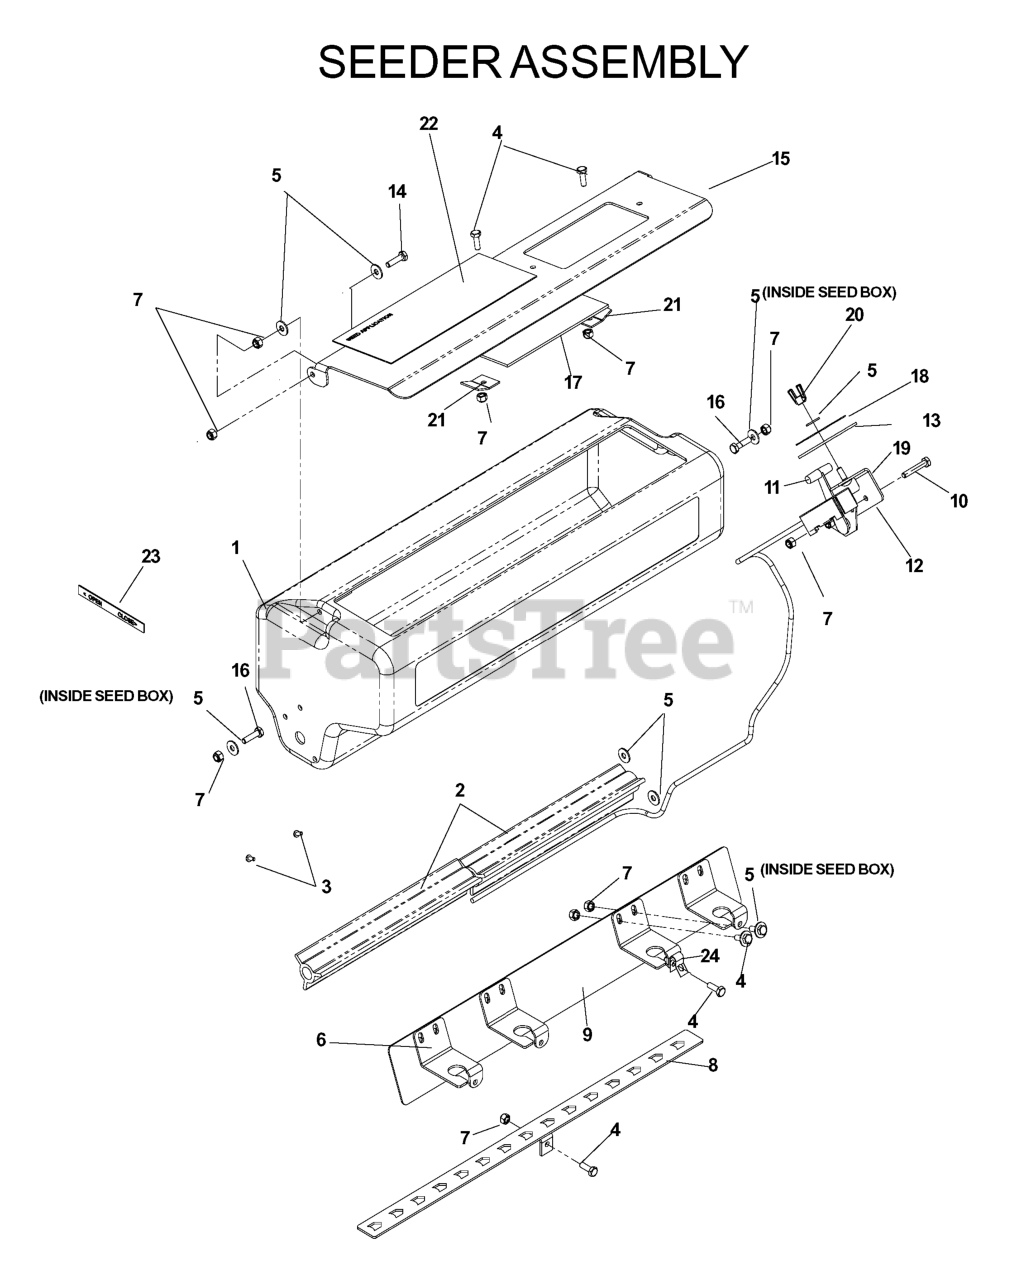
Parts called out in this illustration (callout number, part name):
1	SEED BOX CHARCOAL GREY
3	HR STRIP, 1/8 X 1
4	HCS 1/4C X 3/4 HCS
5	WASHER 1/4 FLAT
7	NUT.1/4-20.HEX.NYLOC.ZD
10	SCW 1/4-20 X 1-1/2 HEX
11	PUSH/PULL ASSY CONTROL
14	HCS 1/4C X 1
15	SEED DOOR ORANGE
16	HCS 1/4 X 1
17	SEED WINDOW
18	DECAL, SEED DIAL
19	RHSNB 1/4C X 3/4
20	WING NUT 1/4
21	WINDOW CLIP
22	DECAL, SEED APPL
23	DECAL, OPEN/CLOSE
24	PUSH PULL CONTROL CLAMP
540053411	RETAINING RING
